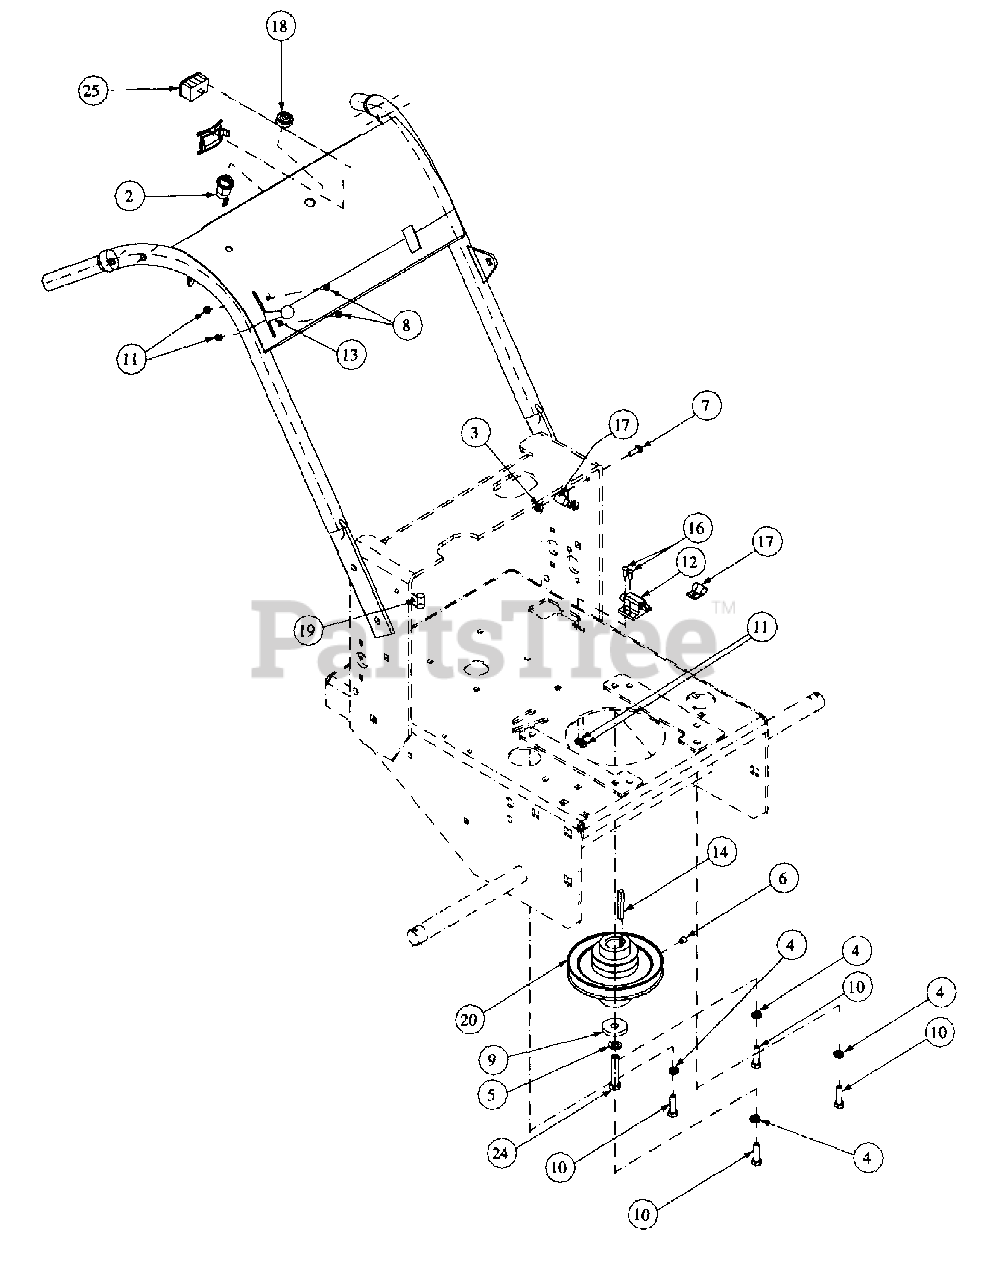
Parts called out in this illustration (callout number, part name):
2	Single Ignition ON/OFF Switch
3	Lock Nut, Nylon Insert, 1/4-20
4	Lock Washer, 5/16
5	Lock Washer, 7/16 Zinc
6	Nylock Screw, 5/16-18 x 3/8
7	Hex Cap Screw, 1/4-20, .75
8	Screw, Hex Washer, 10-32 x 1/2
9	Clutch Washer
10	Cap Screw, 1.25 x 30
11	Lock Nut, Nylon Insert, 10-32
12	Delta Switch
13	Control Throttle w/Detent, 39.2
14	Key Stick, 1/4 x 1/4 x 2
16	Machine Screw, 10-32 x 5/8
17	Support Clamp Tubing, 1/2"
18	Nut, w/Cap, 5/8-32, Ignition
19	Support Clamp, 3/8 OD
20	Double Pulley Gear
21	Belt
22	13HP Kohler Engine,
23	Engine Oil, 10W-40
24	Capscrew, 7/16-20 x 2"
25	Hour Meter
26	Harness Hourmeter
27	Harness Assembly, Kohler Adapter
